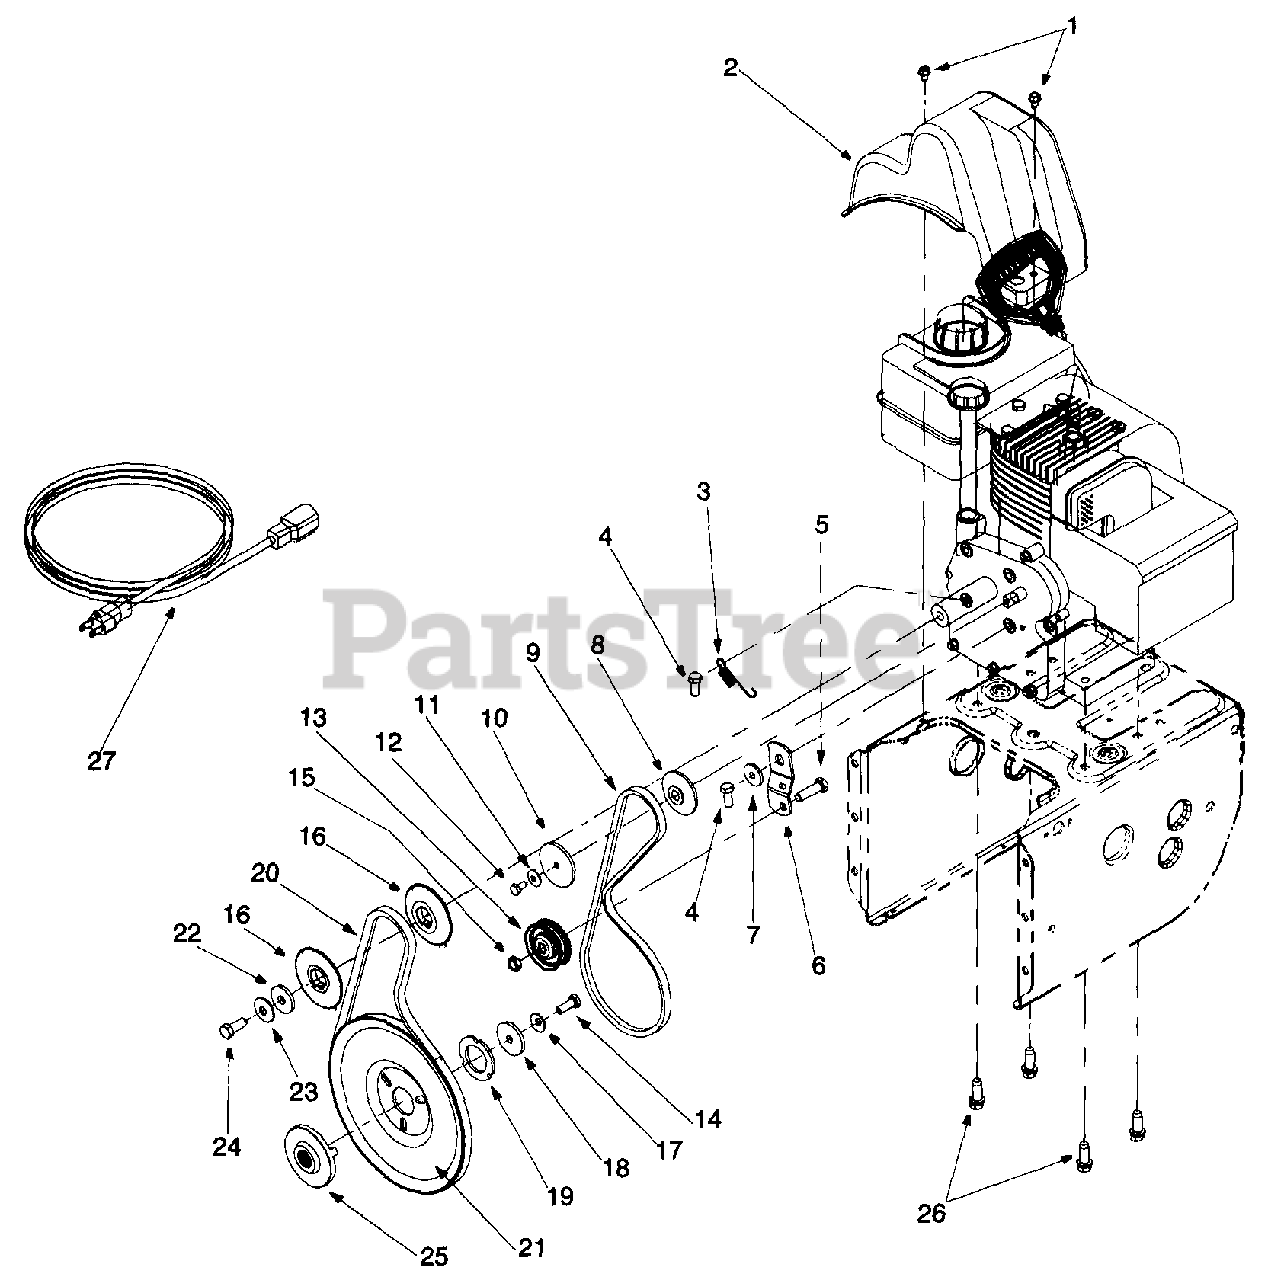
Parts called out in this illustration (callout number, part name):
1	Hex Washer Screw 1/4-20 x.5
2	Belt Cover
3	Extension Spring
4	Hex Screw 5/16-24 x .75
5	Hex Cap Screw 3/8-16 x 1.25
8	Pulley Half
9	V-Belt
10	Pulley Half
11	Bell Washer
12	Hex Cap Screw 1/4-28 x .50
13	Flat Idler
14	Lock Cap Screw 5/16-24
15	Lock Jam Nut 3/8-16
16	Pulley Half
17	Bell Washer
18	Flat Washer
19	Washer
20	Belt
21	Auger Pulley
22	Flat Washer
23	Bell Washer
24	Hex Cap Screw 3/8-24
25	Pulley
26	Hex Washer Screw 3/8-16 x 1.0
27	Extension Cord
